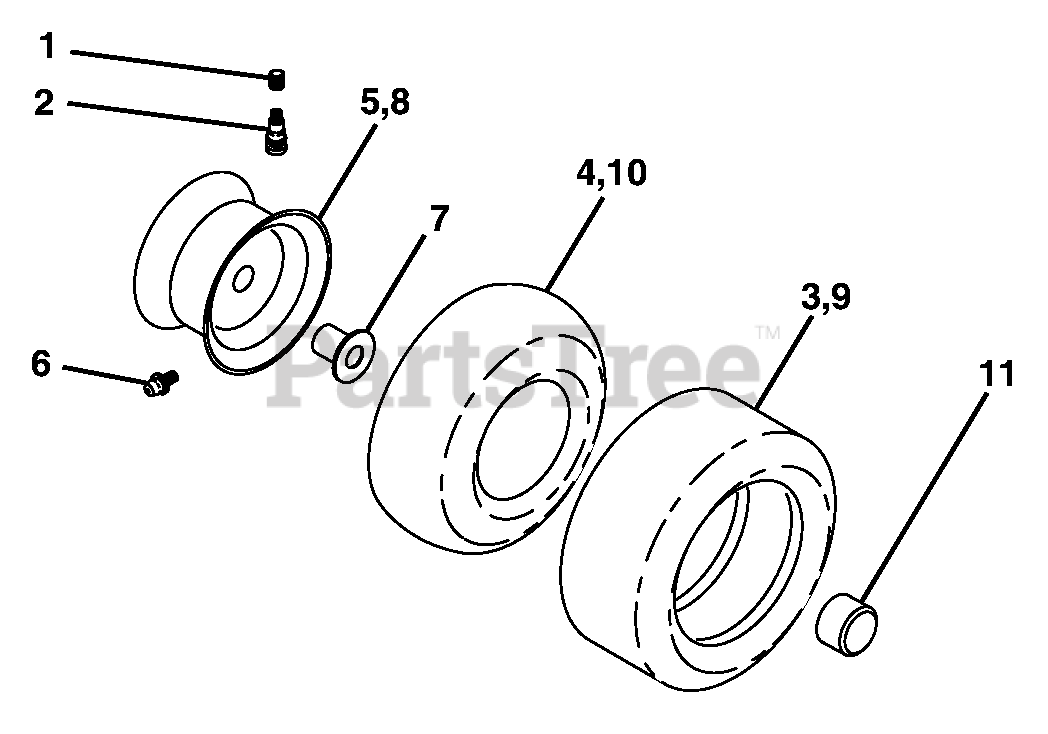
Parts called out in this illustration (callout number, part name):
1	Cap Valve Tire
2	Stem Valve
3	Tire F T 15 x 6 0 - 6 Service
4	Tube Front (Service Item Only)
5	Rim Asm 6" front Service
6	Fitting Grease (Front Wheel Only)
7	Bearing Flange (Front Wheel Only)
8	Rim Asm 8" rear Service
9	Tire R T 20 x 8-8 C Service
10	Tube Rear (Service Item Only)
11	Cap Axle 1 50 x 1 00
